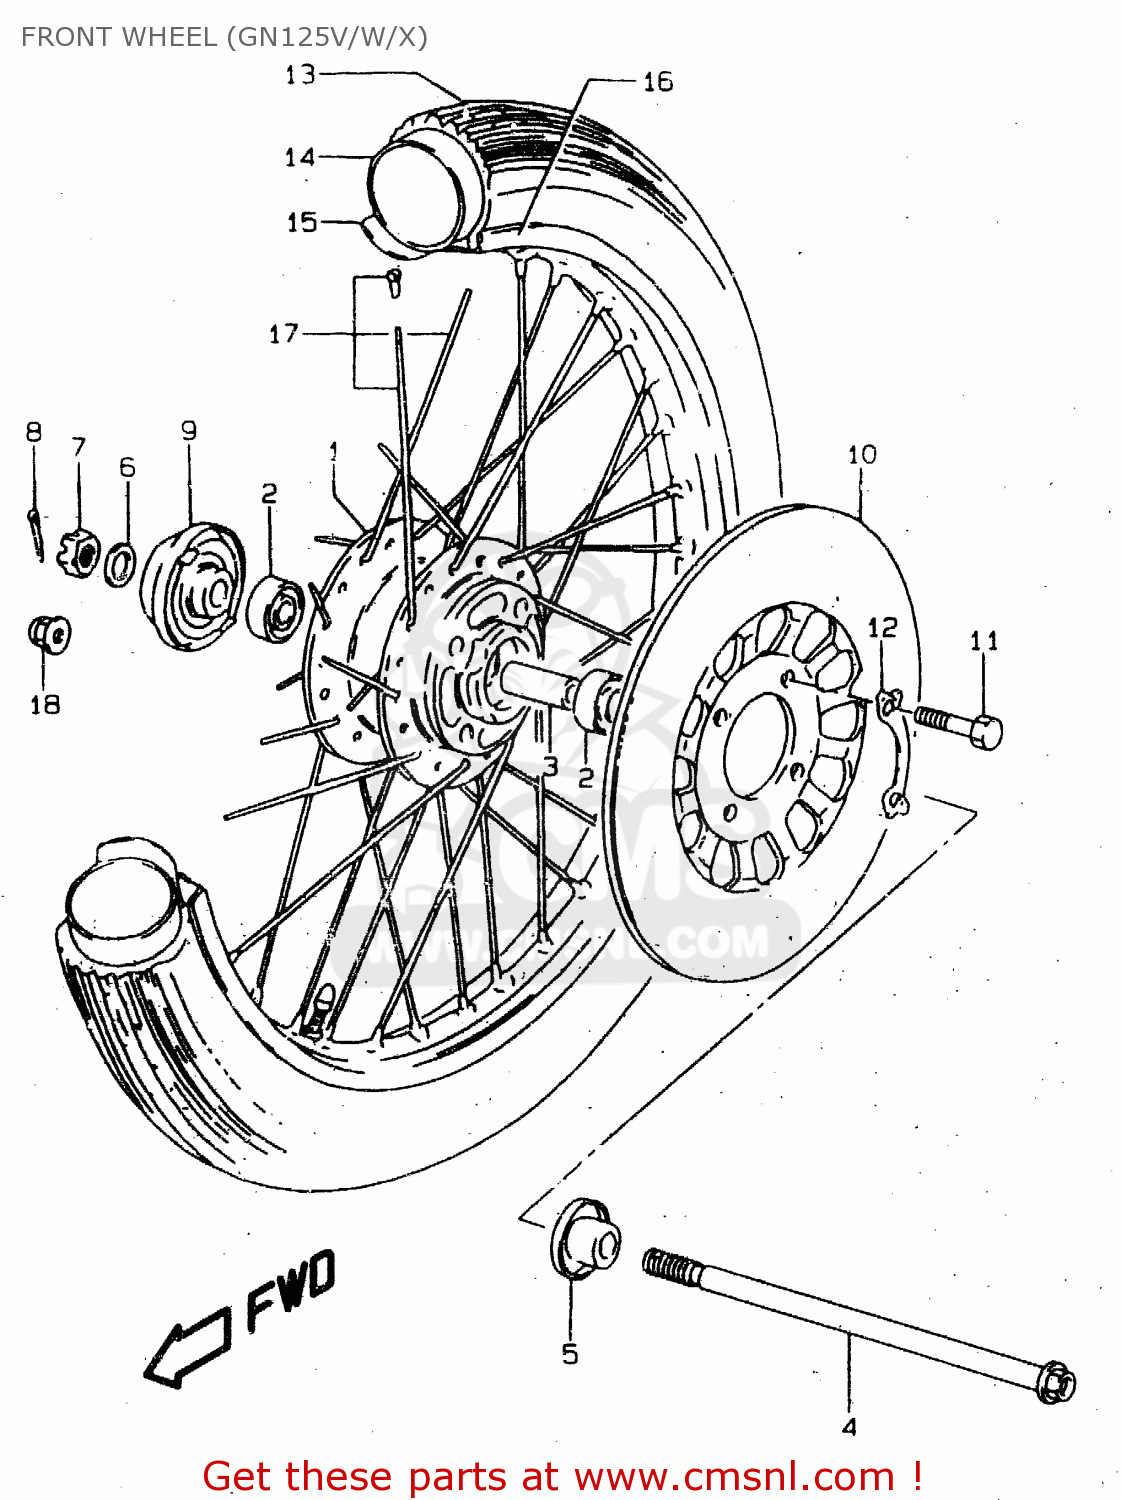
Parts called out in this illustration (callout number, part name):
1	HUB,FR WHEEL
2	BEARING
3	SPACER(12.5X19X52)
4	AXLE,FR
5	SPACER,FR AXLE,L
6	WASHER
7	NUT
8	COTTER PIN
9	BOX ASSY,SPEEDOMETER GEAR
10	DISC,FR BRAKE
11	BOLT(8X25)
12	WASHER
13	TIRE,FR(2.75-18)
14	TUBE,INNER
15	PROTECTOR,INNER TUBE
16	RIM,FR WHEEL
17	SPOKE ASSY,FR
18	NUT 12MM
